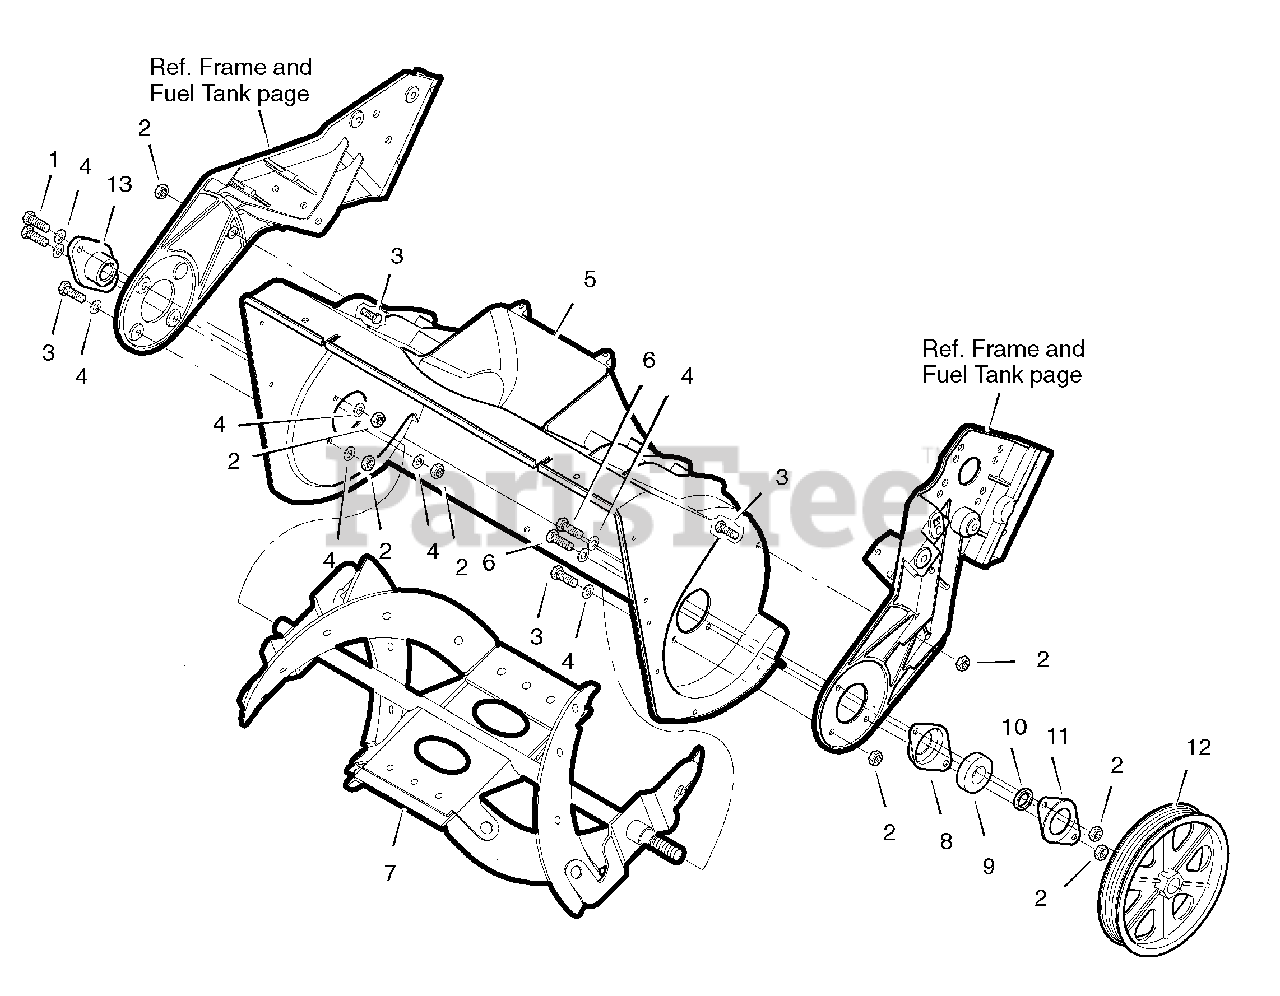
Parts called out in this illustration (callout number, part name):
1	SCREW, 1/4-20 x 1.00
2	NUT, Hex 1/4-20
3	SCREW, 1/4-20 x .75
4	WASHER FLAT 9/32 x 5/8 x 1/16
5	HOUSING ASSEMBLY, Auger
6	SCREW, 1/4-20 x 5/8
7	AUGER ASSEMBLY, 22"
8	RETAINER, Bearing
9	BEARING, Ball
10	SLEEVE, Spacer
11	PLATE, Bearing Retainer
12	PULLEY, Auger Drive V6
13	BEARING, Flange
